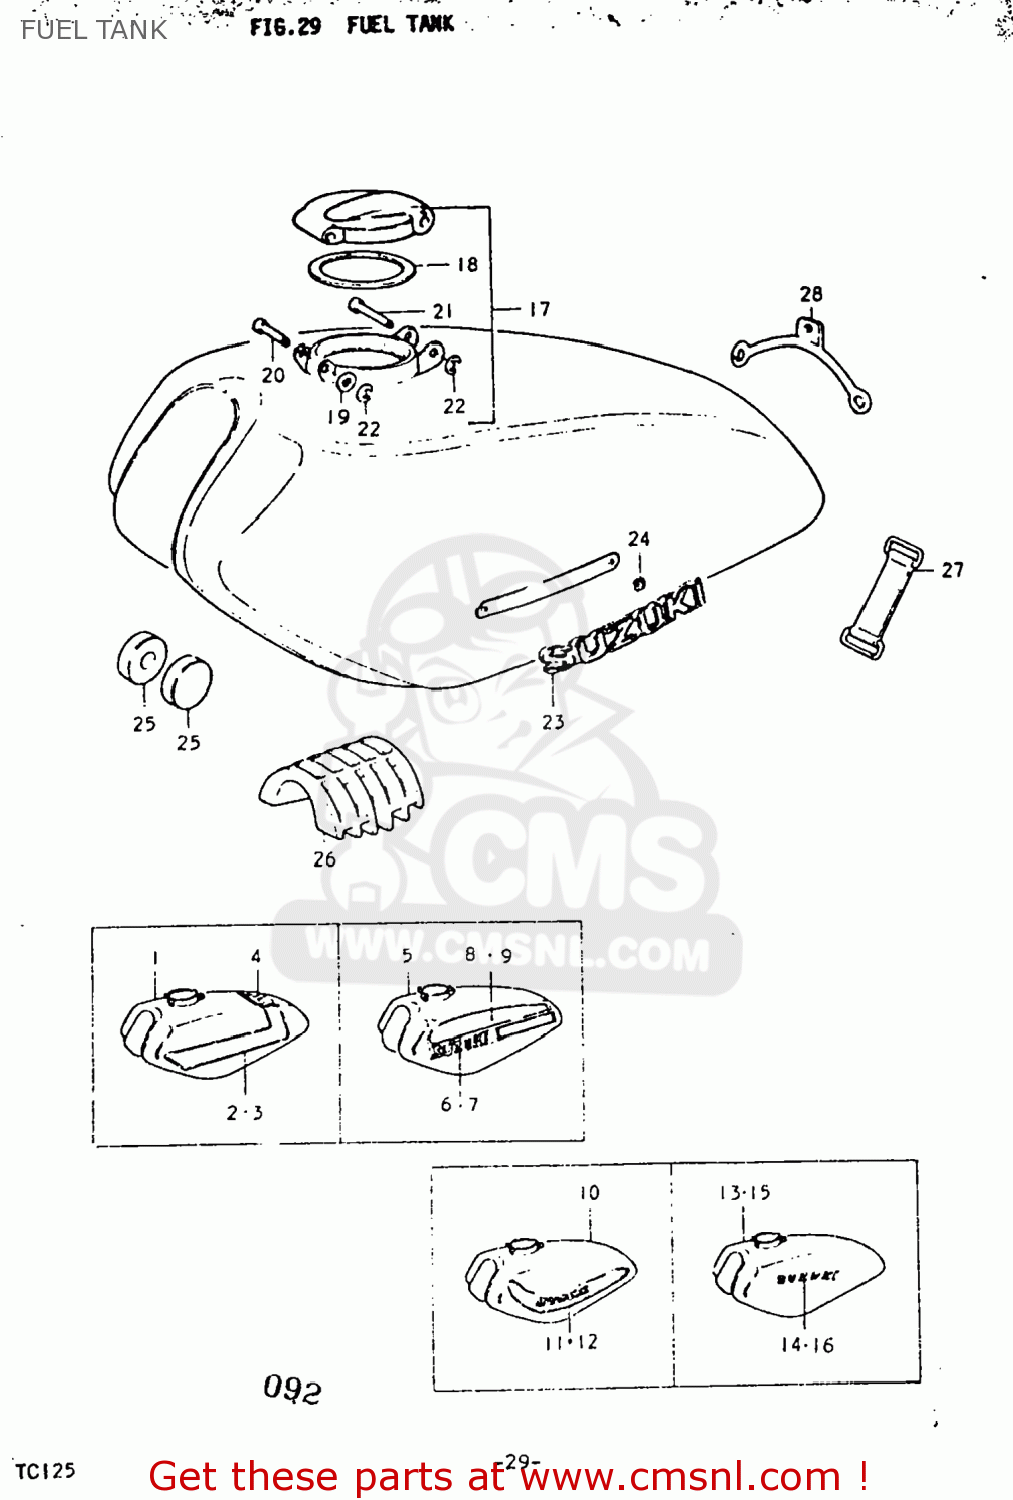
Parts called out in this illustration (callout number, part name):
1	TANK ASSEMBLY,FUEL
2	TAPE,FUEL TANK
3	TAPE,FUEL TANK
5	TANK ASSEMBLY,FUEL
6	EMBLEM
7	EMBLEM,FUEL TANK
8	TAPE,FUEL TANK
9	TAPE,FUEL TANK
10	TANK ASSEMBLY,FUEL
11	TAPE,FUEL TANK
12	TAPE,FUEL TANK
13	TANK ASSEMBLY,FUEL
14	EMBLEM,FUEL TANK
15	TANK ASSEMBLY,FUEL
16	EMBLEM
17	CAP SET,FUEL TANK
18	GASKET (NAS)
19	WASHER
21	PIN,FUEL TANK C
22	E RING
23	EMBLEM
24	NUT
25	CUSHION
26	CUSHION
27	BAND
28	BAND
